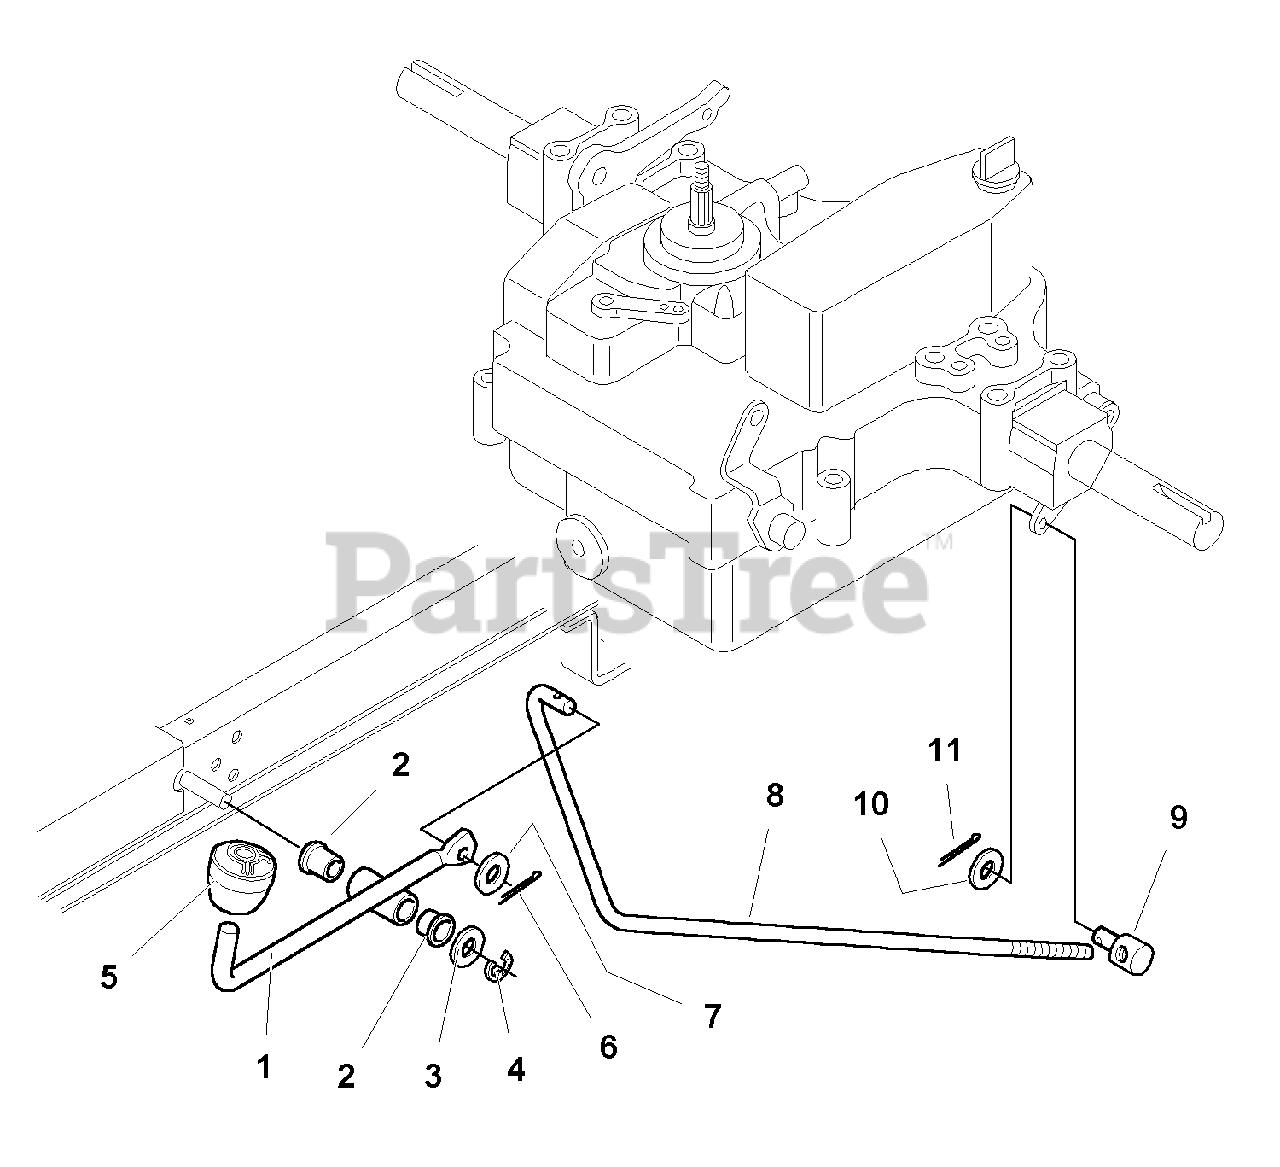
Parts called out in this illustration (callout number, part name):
1	PEDAL & HUB ASSEMBLY
2	BUSHING, Nylon
3	WASHER, 1/2
4	E-CLIP, Retaining Ring
5	KNOB, Diff Lock, Plastic
6	PIN, Cotter
7	WASHER, 5/16
8	ROD, Diff Lock
10	WASHER, 5/16
11	PIN, Cotter
